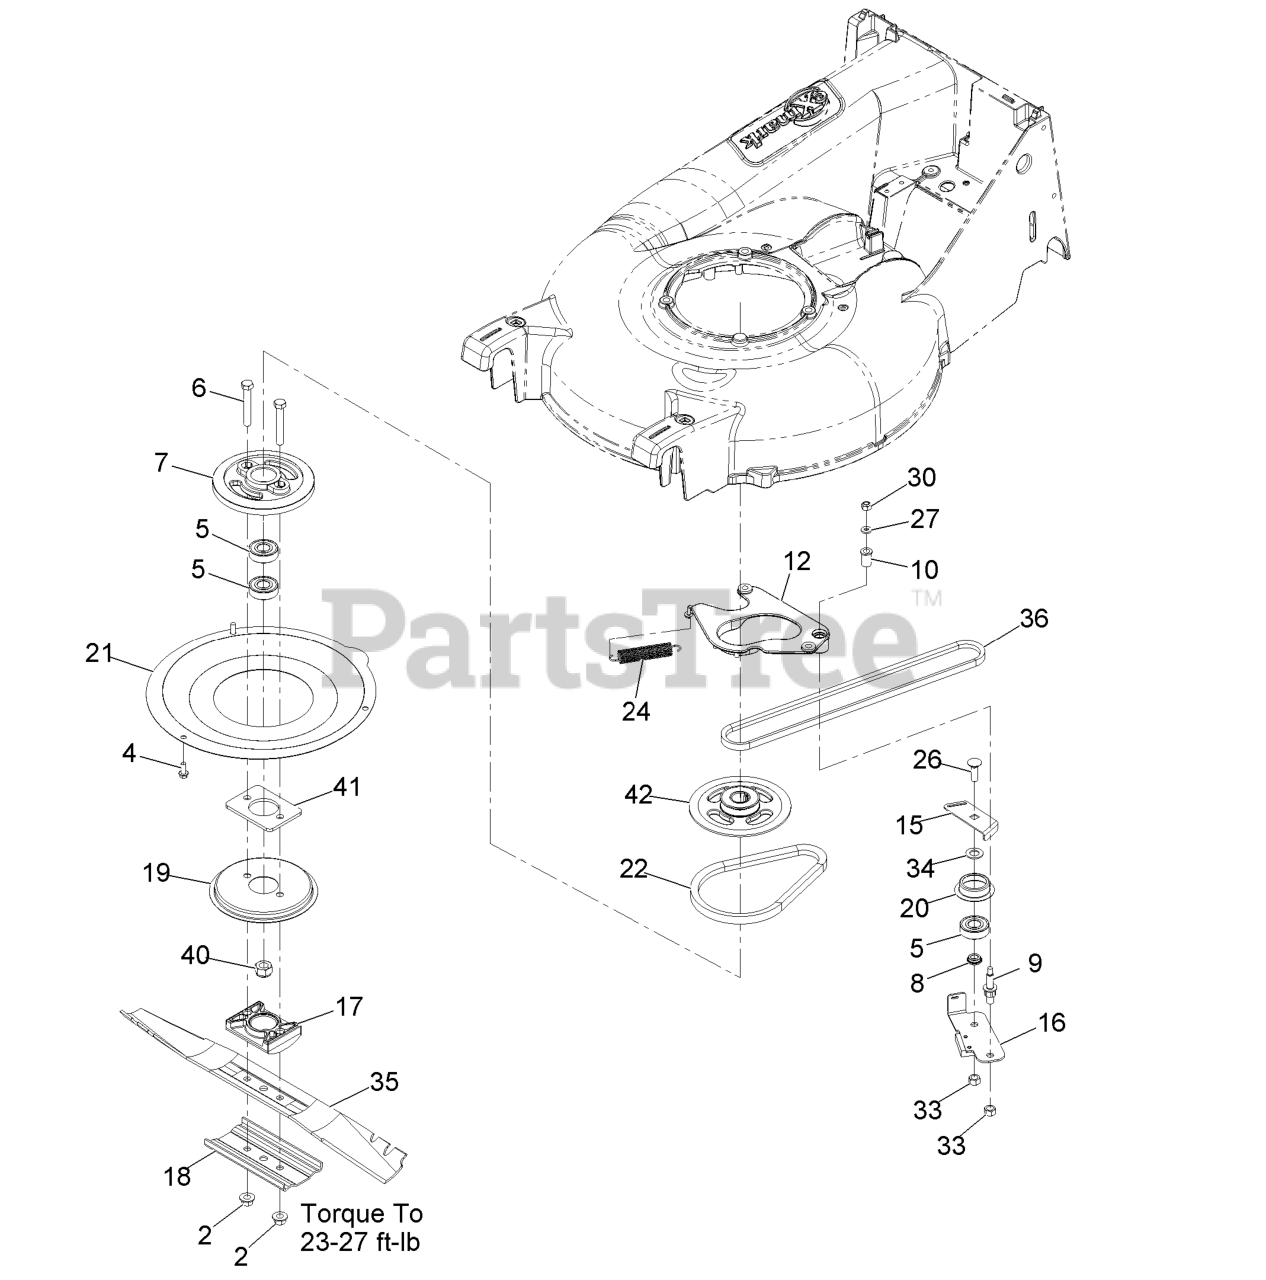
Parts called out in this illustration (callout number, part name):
2	Nut-Hex 3/8-24 Lock
4	SCREW-HWH
6	SCREW-HH
8	SPACER-BEARING
9	BOLT-SHOULDER
10	BUSHING
12	PLATE,ANCHOR
15	PLATE-GUIDE
17	SUPPORT-BLADE
18	SUPPORT-BLADE
19	DISC
20	RETAINER-BELT
21	COVER-BBC
22	BELT
24	SPRING-TENSION, BRAKE
26	SCREW-CARR
27	WASHER-FLAT
30	NUT-LOCK, NI
33	LOCKNUT
34	SPACER
36	BELT,3L P21 DRIVE
40	NUT-HEX
